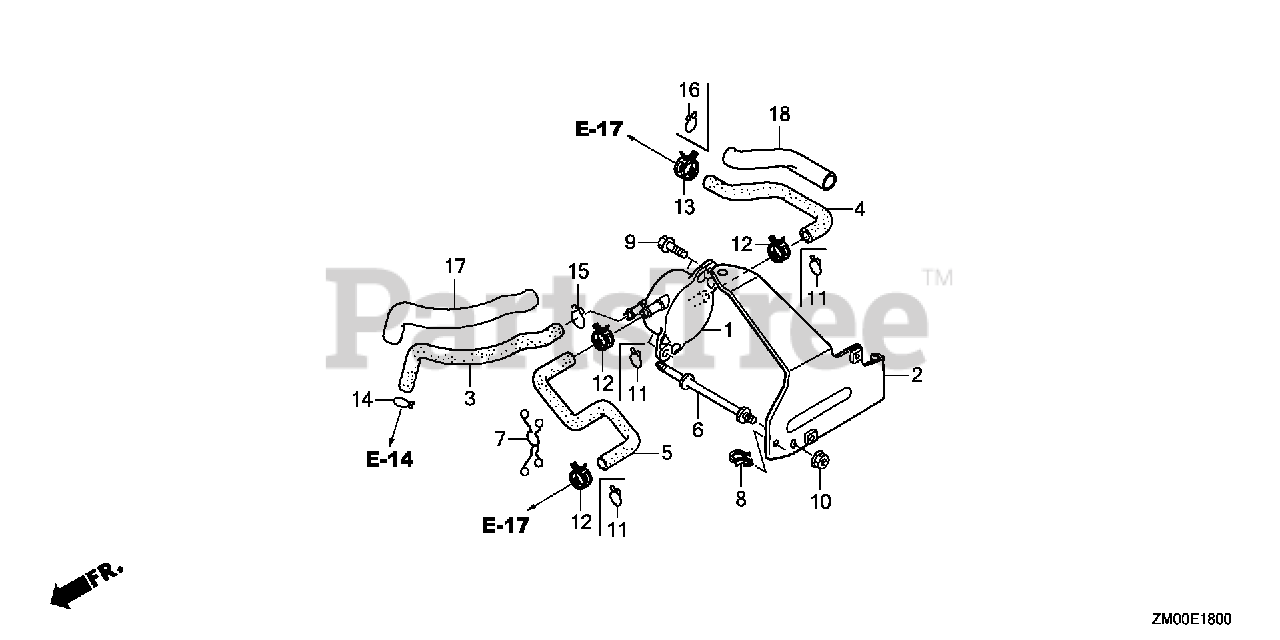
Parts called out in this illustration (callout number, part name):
1	PUMP ASSY., FUEL (MSDS)
2	STAY, FUEL PUMP
3	TUBE, DIAPHRAGM
4	TUBE, FUEL TANK (FKM)
5	TUBE B, FUEL (FKM)
6	BOLT, STUD
7	CLIP, PURSE LOCK
8	CLIP, WIRE HARNESS
9	SCREW-WASHER (5X14)
10	NUT, FLANGE (6MM)
12	CLAMP, TUBE (D10)
13	CLAMP, TUBE (D12)
14	CLIP, TUBE (C8)
15	CLIP, TUBE (C9)
17	BULK HOSE, VINYL (9X11X3000) (9X11X210)
18	BULK HOSE, VINYL (13X15X8000) (13X15X90)
